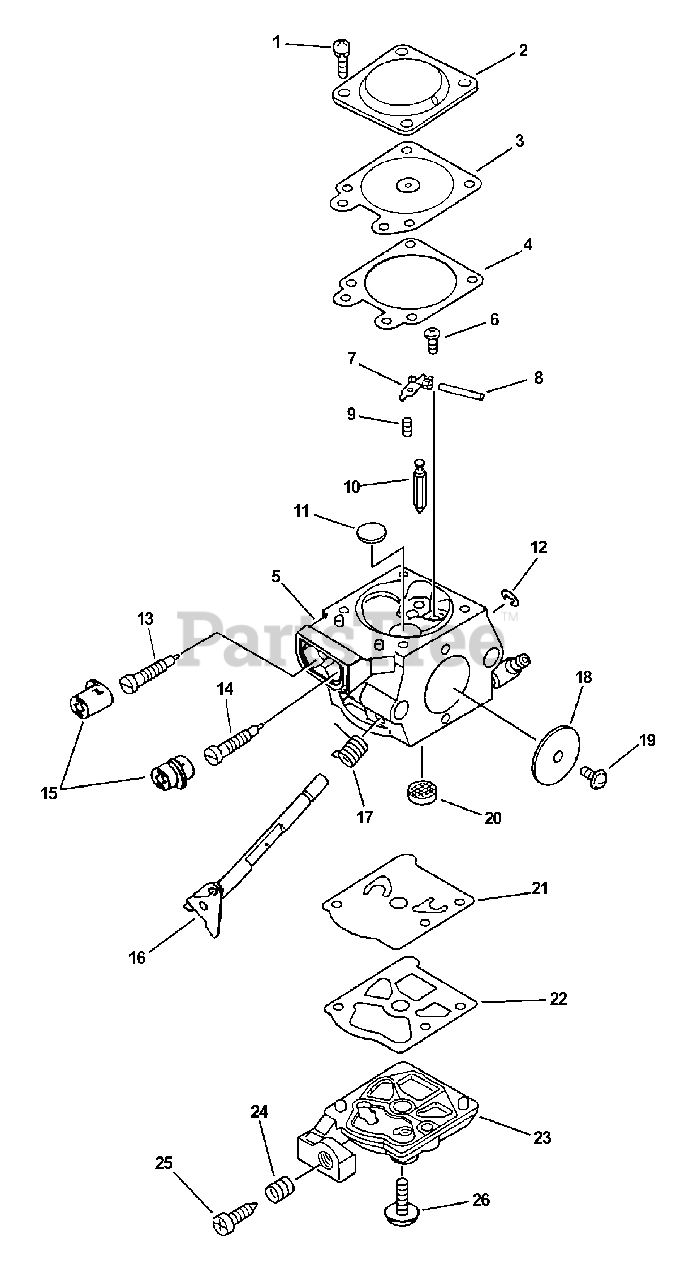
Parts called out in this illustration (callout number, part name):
2	COVER, METERING DIAPHRAGM
3	DIAPHRAGM, METERING
4	GASKET, METERING
5	BODY, CARBURETOR
6	SCREW, METERING LEVER PIN
7	LEVER, METERING
8	PIN, METERING LEVER
9	SPRING, METERING LEVER
10	VALVE, INLET NEEDLE
11	PLUG, WELCH
13	NEEDLE, MIXTURE
14	NEEDLE, MIXTURE
15	CAP, LIMITER
16	SHAFT, THROTTLE
17	SPRING, THROTTLE RETURN
18	VALVE, THROTTLE
20	STRAINER
23	COVER, FUEL PUMP
24	SPRING, IDLE ADJUST
25	SCREW, IDLE ADJUST
26	REPAIR KIT, CARBURETOR
26	GASKET / DIAPHRAGM KIT
